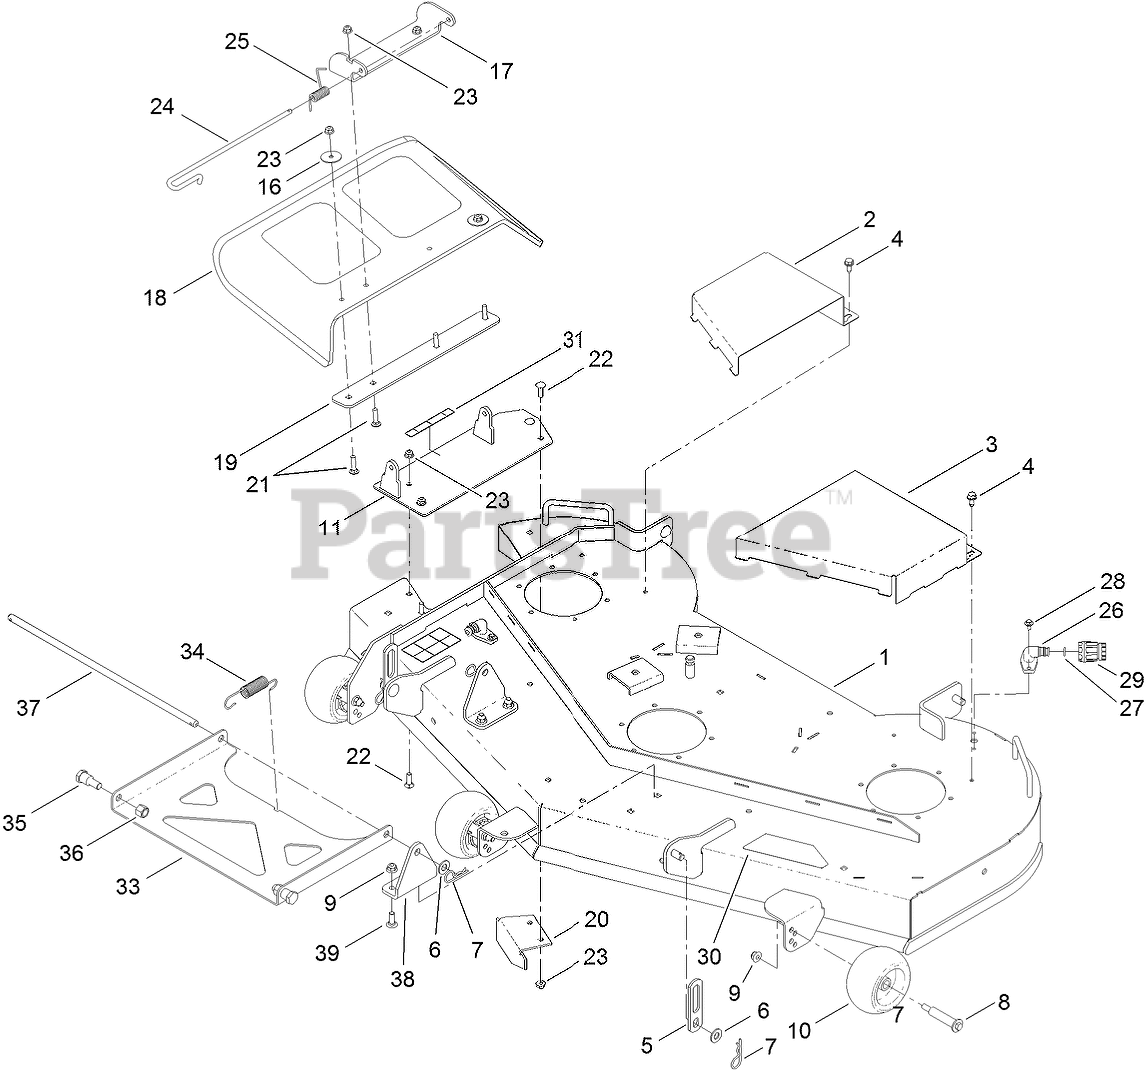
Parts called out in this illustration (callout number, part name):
1	54 INCH DECK AND DECAL ASM
2	COVER-BELT, RH
3	COVER-BELT, LH
4	SCREW-HWHTF
5	LINK-LIFT
6	WASHER-FLAT
7	PIN-COTTER
8	BOLT-SHOULDER
9	NUT-HF, NI
10	ROLLER-SCALP, ANTI
11	PLATE-COVER
16	WASHER-FLAT
17	BRACKET-DEFLECTOR, UPPER
18	DEFLECTOR
19	PLATE-DEFLECTOR
20	BAFFLE-CUTOFF
21	SCREW-CARR
22	SCREW-CARR
23	NUT-HF, NI
24	PIN-CHUTE
25	SPRING-TORSION
26	FITTING-WASHOUT
27	O-RING
28	SCREW-HHFTF
29	CONNECTOR-HOSE
31	DECAL-DANGER
33	PAN-PIVOT, DECK
34	SPRING-EXTENSION
35	BOLT-SHOULDER, HH
36	NUT-LOCK, NI
37	ROD-DECK, PIVOT
38	BRACKET-PIVOT, FRONT
39	SCREW-CARR
